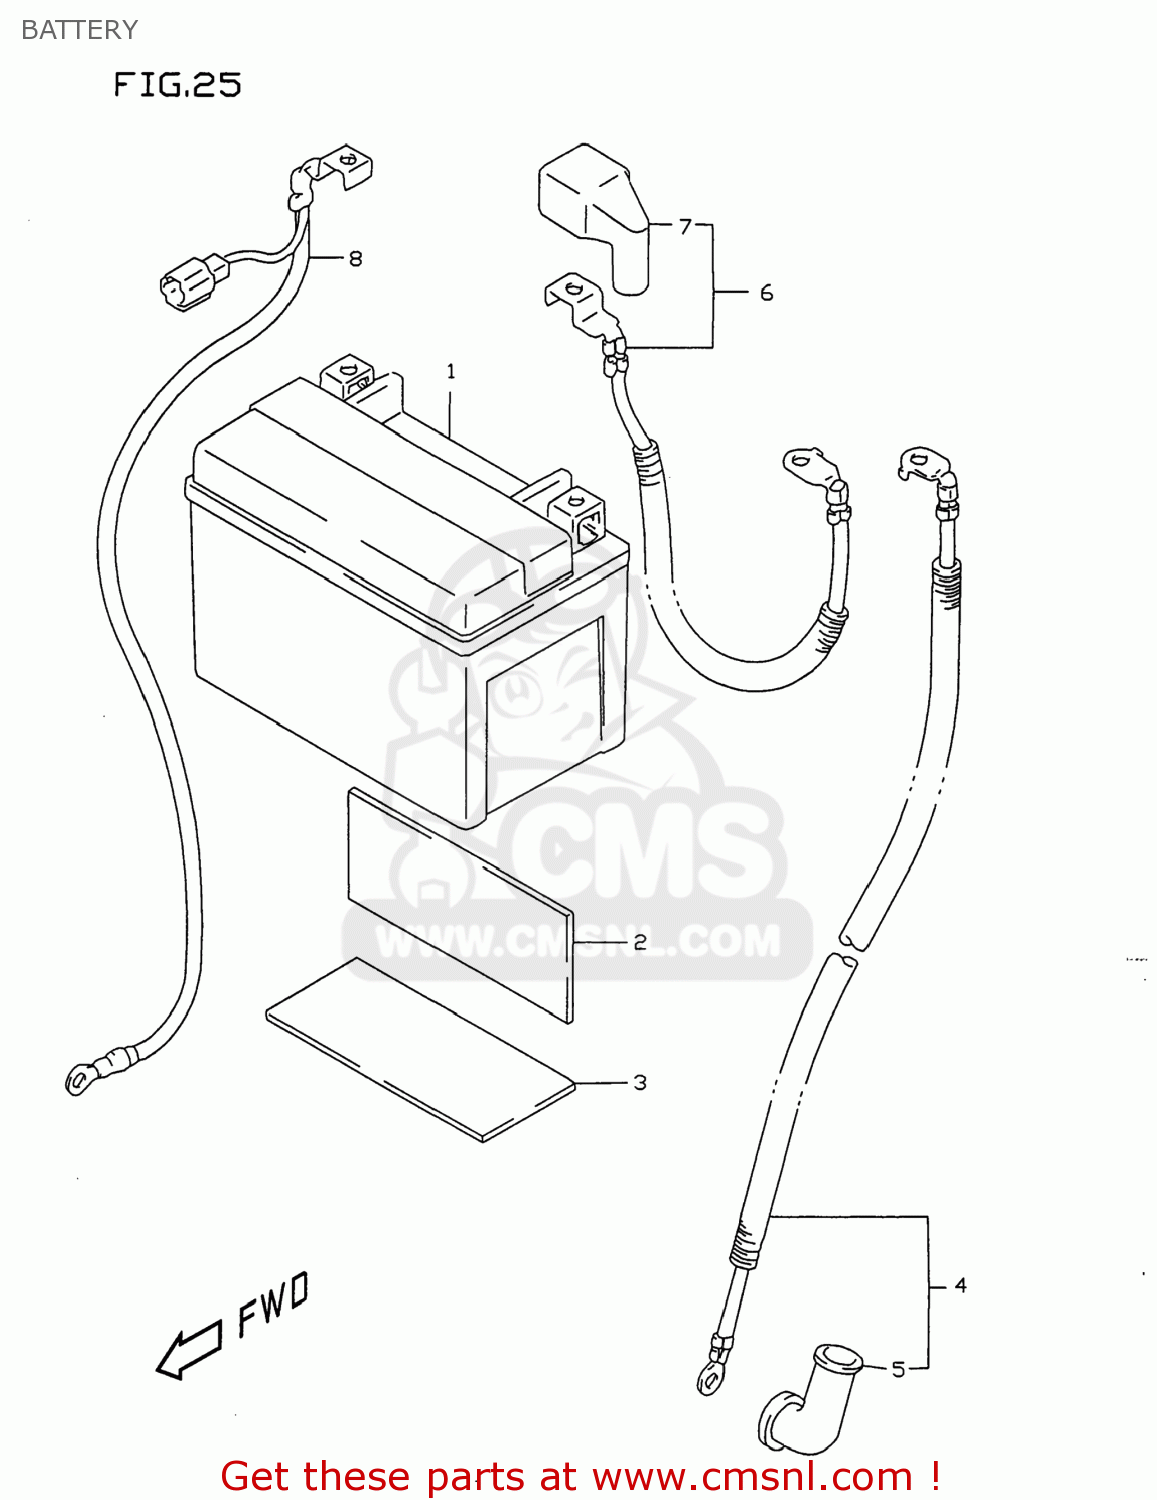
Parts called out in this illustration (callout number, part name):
1	BATTERY ASSEMBLY (12V) FTX
2	PROTECTOR(170X95X3.0)
3	CUSHION,BATTERY(90X45X18)
4	WIRE,STARTER MOTOR LEAD
5	CAP,STARTER MOTOR LEAD
6	WIRE,BATTERY PLUS LEAD
7	CAP,BATTERY PLUS TERMINAL
8	WIRE,BATTERY MINUS
